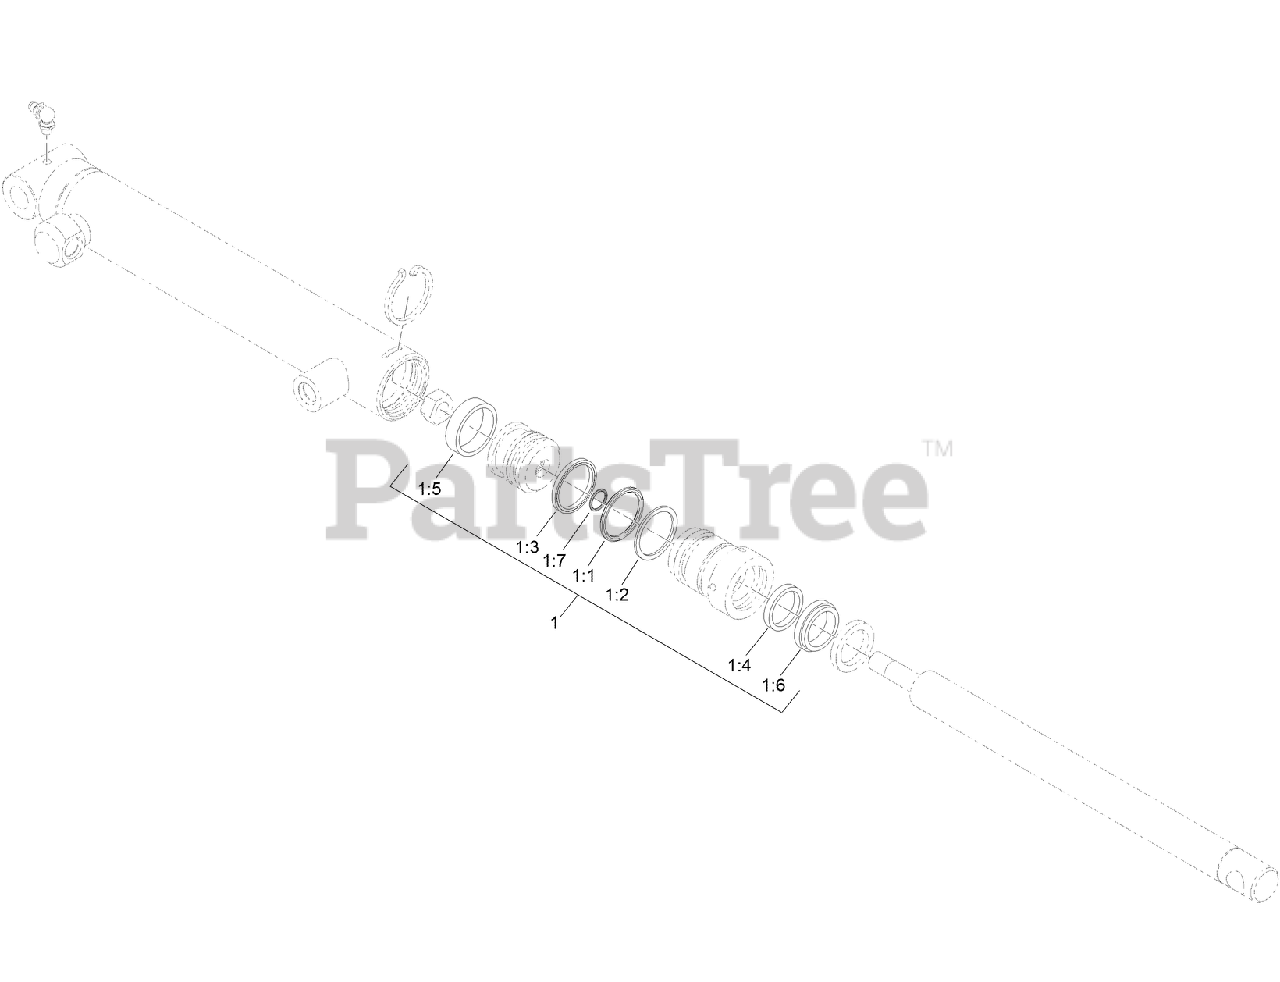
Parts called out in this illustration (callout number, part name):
1	REPAIR KIT
1:1	Deck ASM
1:2	Deck ASM
1:3	Deck ASM
1:4	Deck ASM
1:5	BT SEAL
1:6	Deck ASM
1:7	Deck ASM
